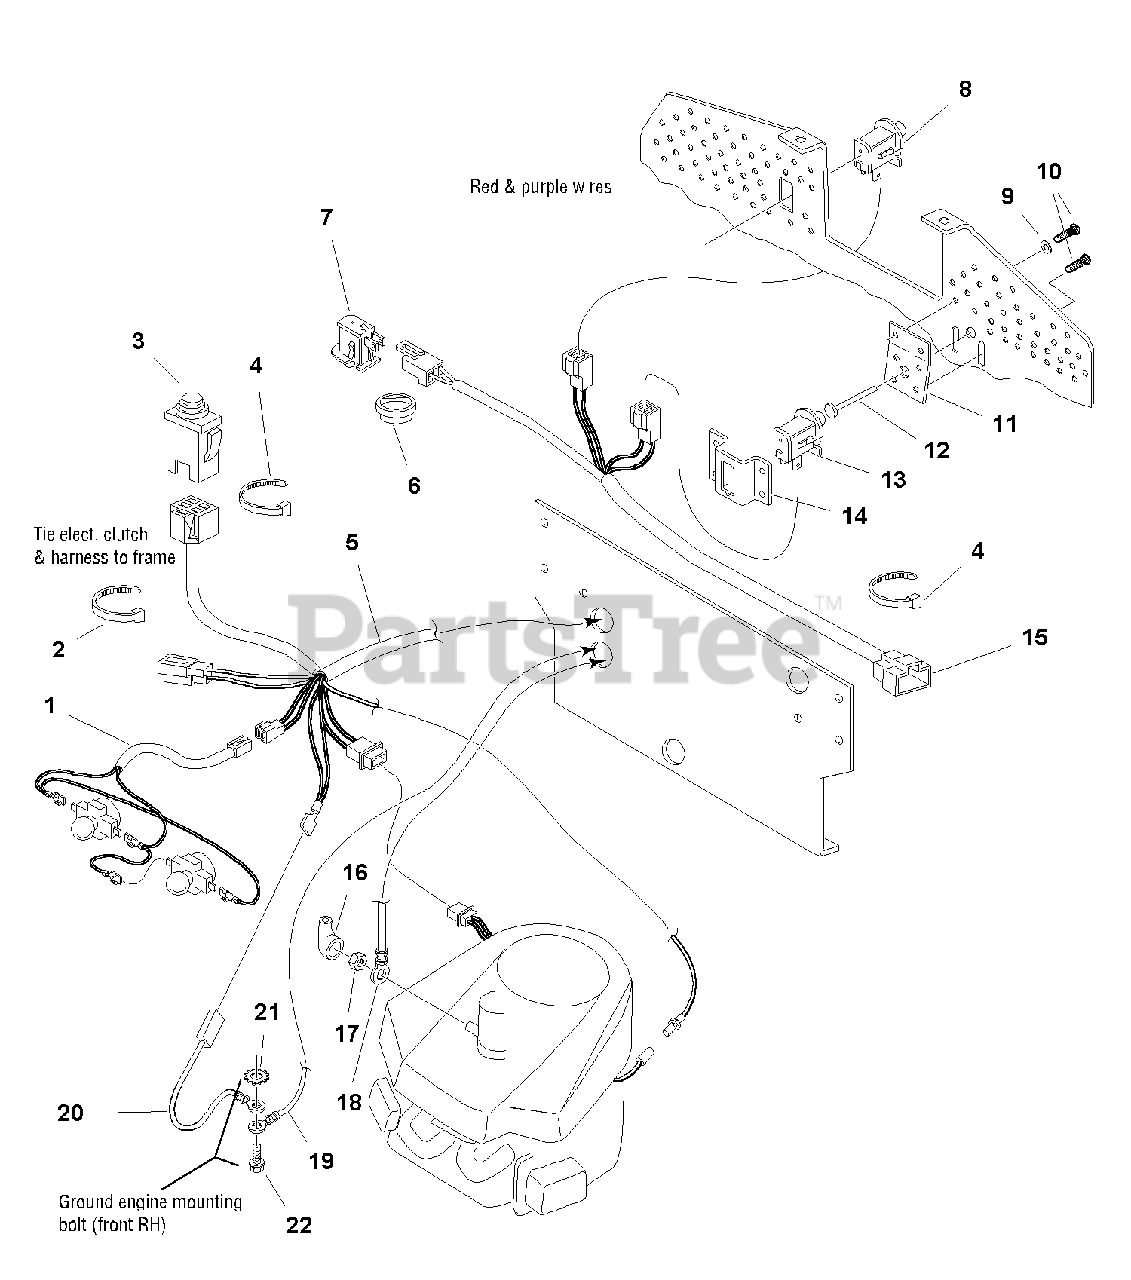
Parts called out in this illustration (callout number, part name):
1	HARNESS, Wiring For Headlights
2	TIE, Self Locking, 3-5/8" Long
3	SWITCH, Push Button Foot Pedal
4	TIE, Self Locking, 7-5/16" Long
5	HARNESS, Wiring
6	BUSHING, Snap
7	SWITCH, Push Button Seat Switch
8	SWITCH, Push Button Gray w/Boot, Safety
9	WASHER, Flat, 1/4
10	CAPSCREW, Hex Washer Head, Taptite,1/4-20 x 1/2
11	PLATE, Cover Hopper Switch
12	ROD & WASHER ASSEMBLY, Hopper Switch
13	SWITCH, Push Button, Snap In, Grass Catcher Alarm
14	BRACKET, Hopper Switch
15	WIRE ASSEMBLY, Rear Bagger
16	BOOT, Insulator, Battery Terminal
17	NUT, Hex 1/4-20
18	CABLE, # 6 x 25 Long, (2) Ring Terminals
19	CABLE, # 6 x 26 Long, 1/4 & 3/8 Ring Terms
20	WIRE ASSEMBLY
21	LOCKWASHER, External Tooth, 3/8
22	CAPSCREW, Hex Washer Head, Taptite, 3/8-16 x 1 1/2
